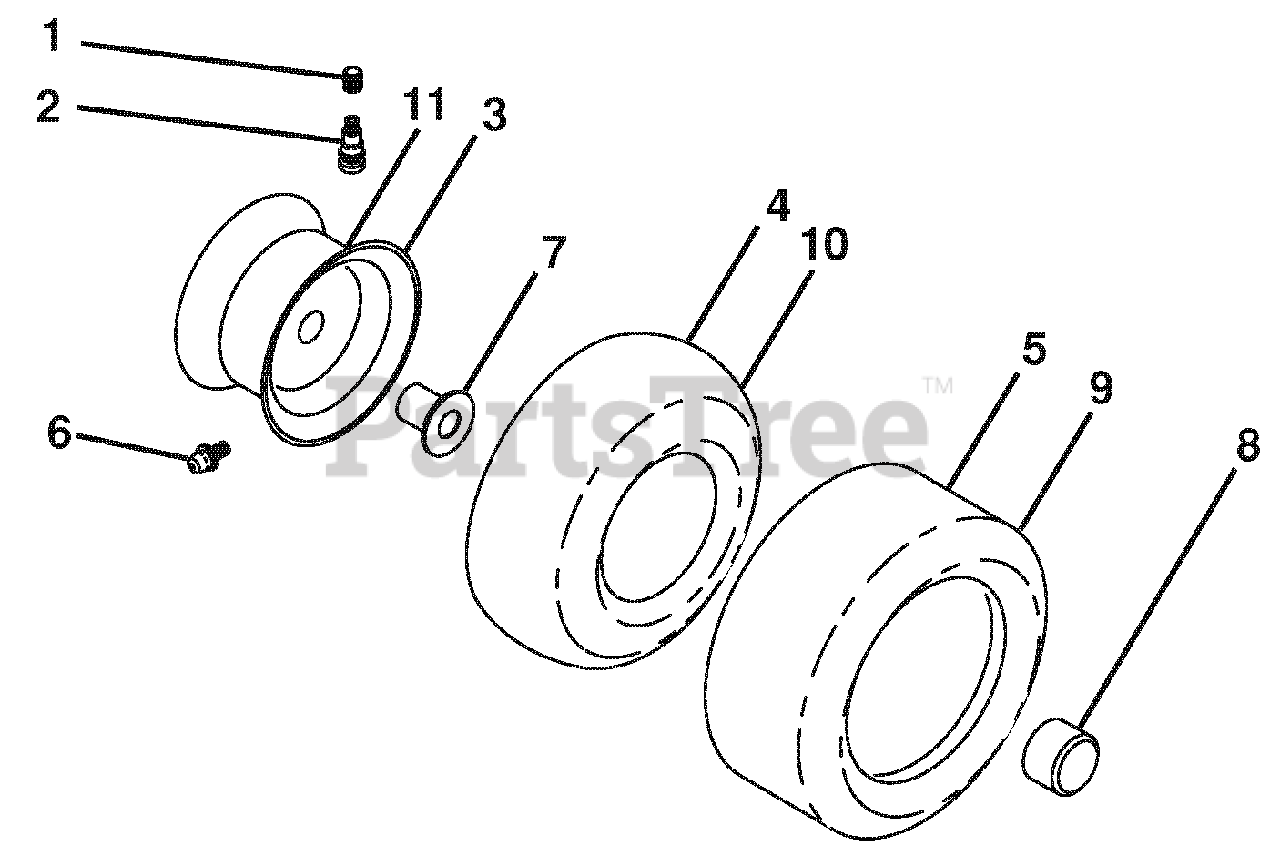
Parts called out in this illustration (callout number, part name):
1	CAP.VALVE.TIRE
2	STEM.VALVE
3	RIM ASSEMBLY 6" FRONT
4	TUBE, FRONT(SERVICE ITEM ONLY)
5	TIRE.F.TS.15 X 6.0 - 6.SERVICE
6	FITTING, GREASE
7	BEARING FLANGE
8	CAP AXLE (FRONT WHEEL ONLY)
9	TIRE.R.TS.20 X 8-8.C.SERVICE
10	TUBE, REAR
11	RIM ASSEMBLY 8" REAR
